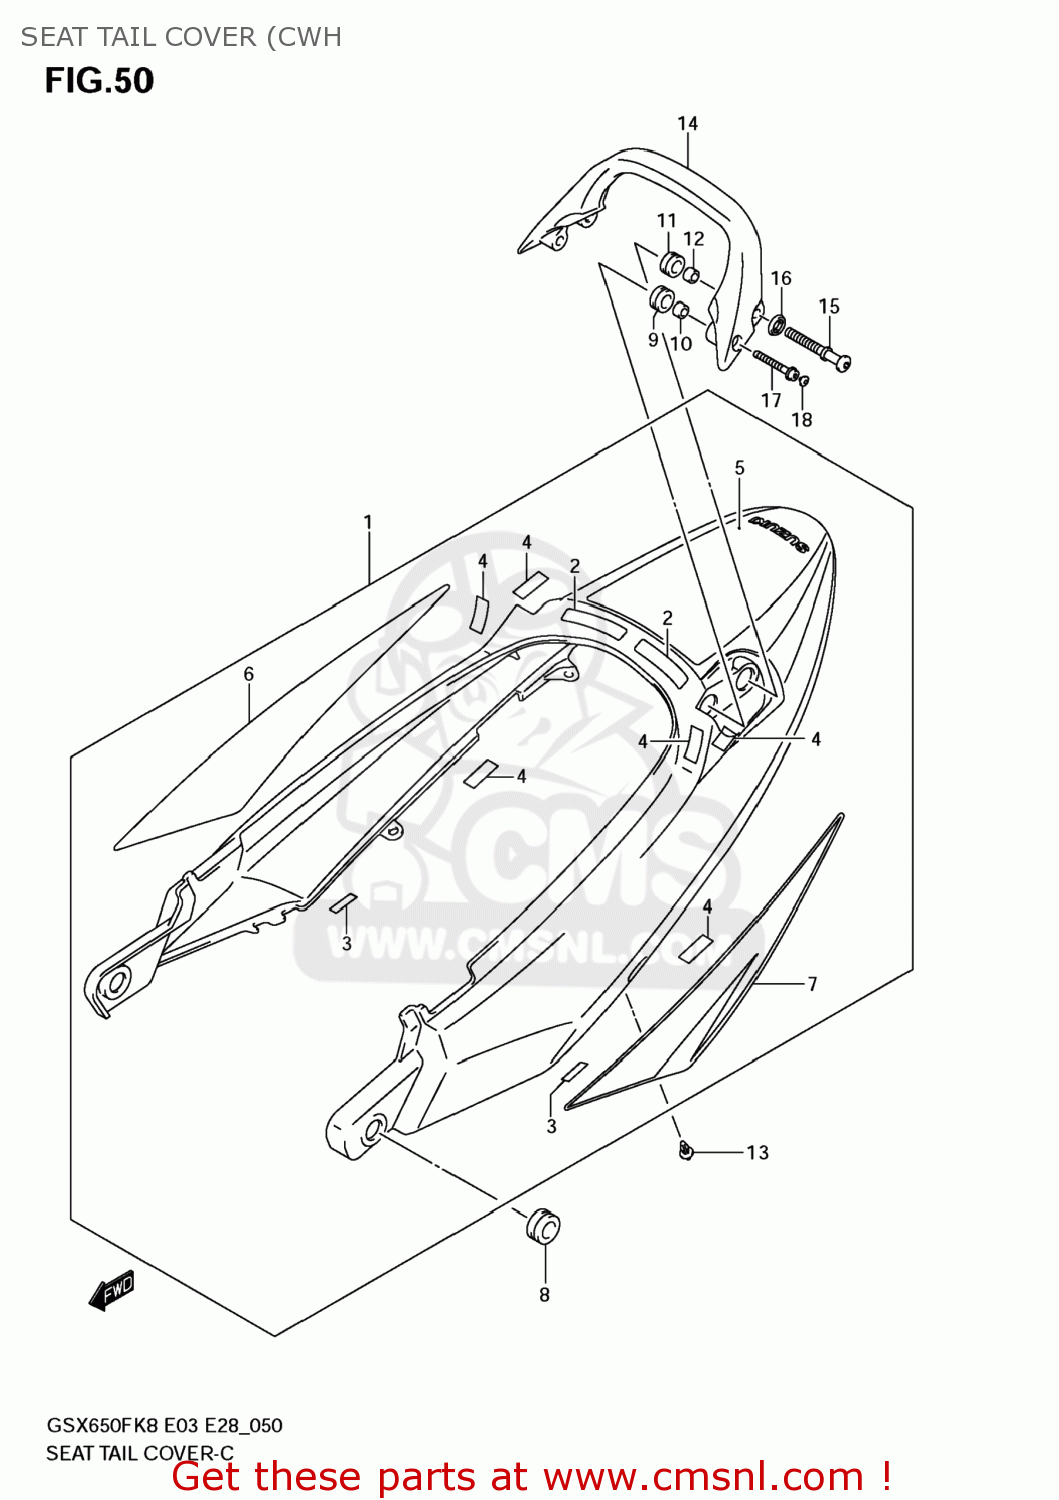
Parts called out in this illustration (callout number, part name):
1	COVER ASSY,SEAT TAIL(WHITE)
2	TAPE,COVER
3	TAPE,SEAT TAIL COVER
4	PROTECTOR,FRAME COVER
5	TAPE,SEAT TAIL COVER CTR
6	TAPE,SEAT TAIL COVER,R
7	TAPE,SEAT TAIL COVER,L
8	CUSHION
9	CUSHION
10	SPACER(6.5X12X9)
11	CUSHION
12	SPACER,8.5X14X9
13	CLIP(BLACK)
14	DUOGREEP
15	HOOK,PILLION RIDER HANDLE
16	WASHER,HOOK
17	BOLT
18	CAP(OD:10)
